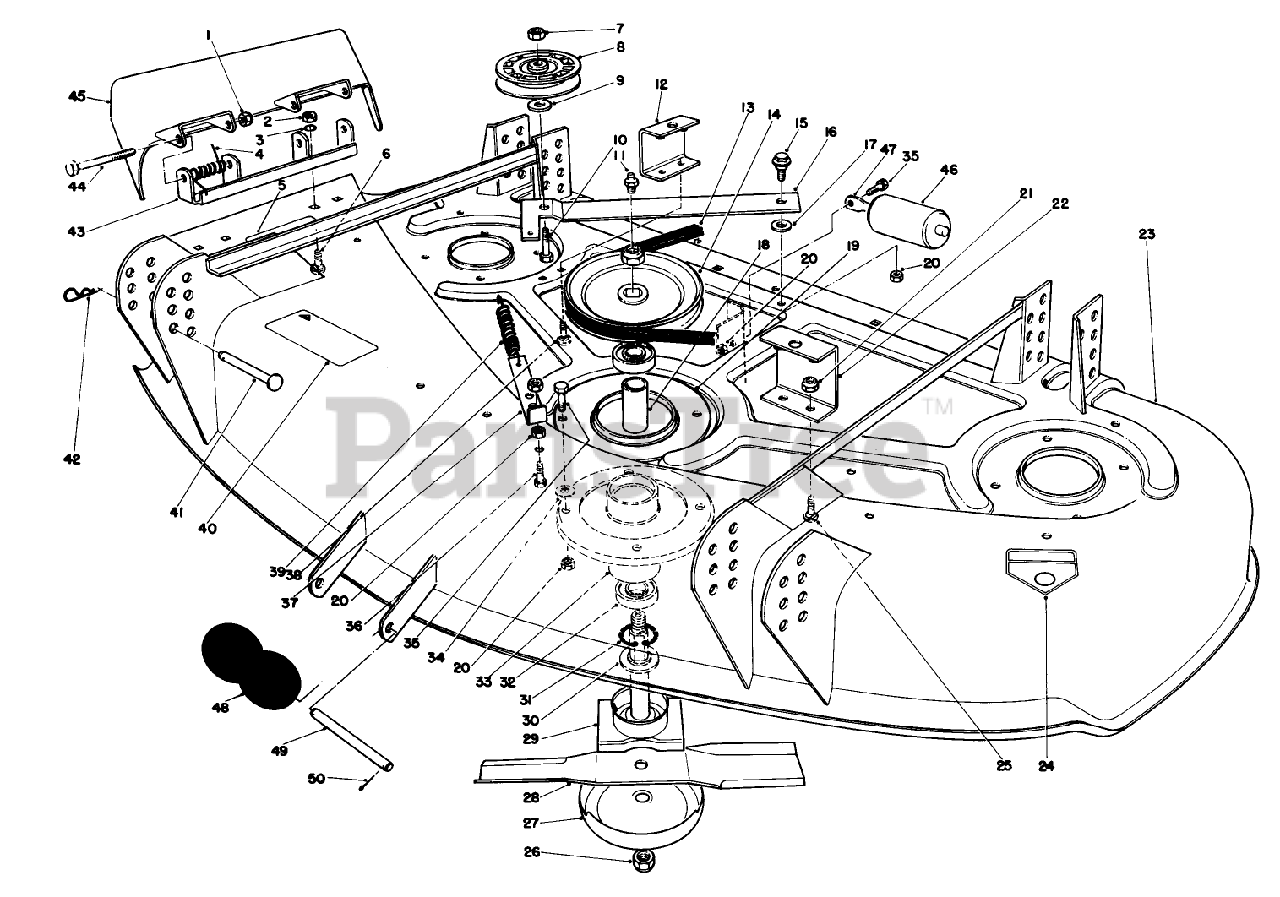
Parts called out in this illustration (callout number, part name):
1	NUT-HEX
2	NUT-HEX
3	WASHER-LOCK
4	SPRING
5	DECAL-CAUTION, DEFLECTOR
6	BOLT-CARR
7	NUT-LOCK, CONE
8	Pulley
9	WASHER-FLAT
10	SCREW-HH
11	FITTING-GREASE
12	Bracket-Cover RH
13	V-BELT-DECK
14	DECK PULLEY
15	SCREW-SHOULDER
16	Lever-Deck
17	WASHER
18	BEARING SPACER
19	DECK RING
20	NUT-LOCK, CONE
21	NUT-LOCK, NI
22	Bracket-Cover LH
23	44" Deck Assembly
24	DECAL-DANGER
25	SCREW-CARR
26	NUT-LOCK NI
27	Cup
28	Blade
29	SPDL/BLD RET.WA
30	SPACER-SPINDLE
31	RING-RETAINING
32	BEARING-BALL
33	Spindle
34	WASHER-FLAT
35	SCREW-HH
36	SCREW-HH
37	Anchor-Deck Spring
38	SCREW-CARR
39	SPRING-EXTENSION, DECK
40	CAUTION DECAL
41	PIN-CLEVIS
42	PIN-HAIR
43	PIVOT BRKT WA R/B
44	SCREW-HH
45	Deflector-Grass
46	ROLLER-DECK
47	ROD-ROLLER
48	ROLLER
49	SHAFT-ROLLER
50	Pin-Cotter
